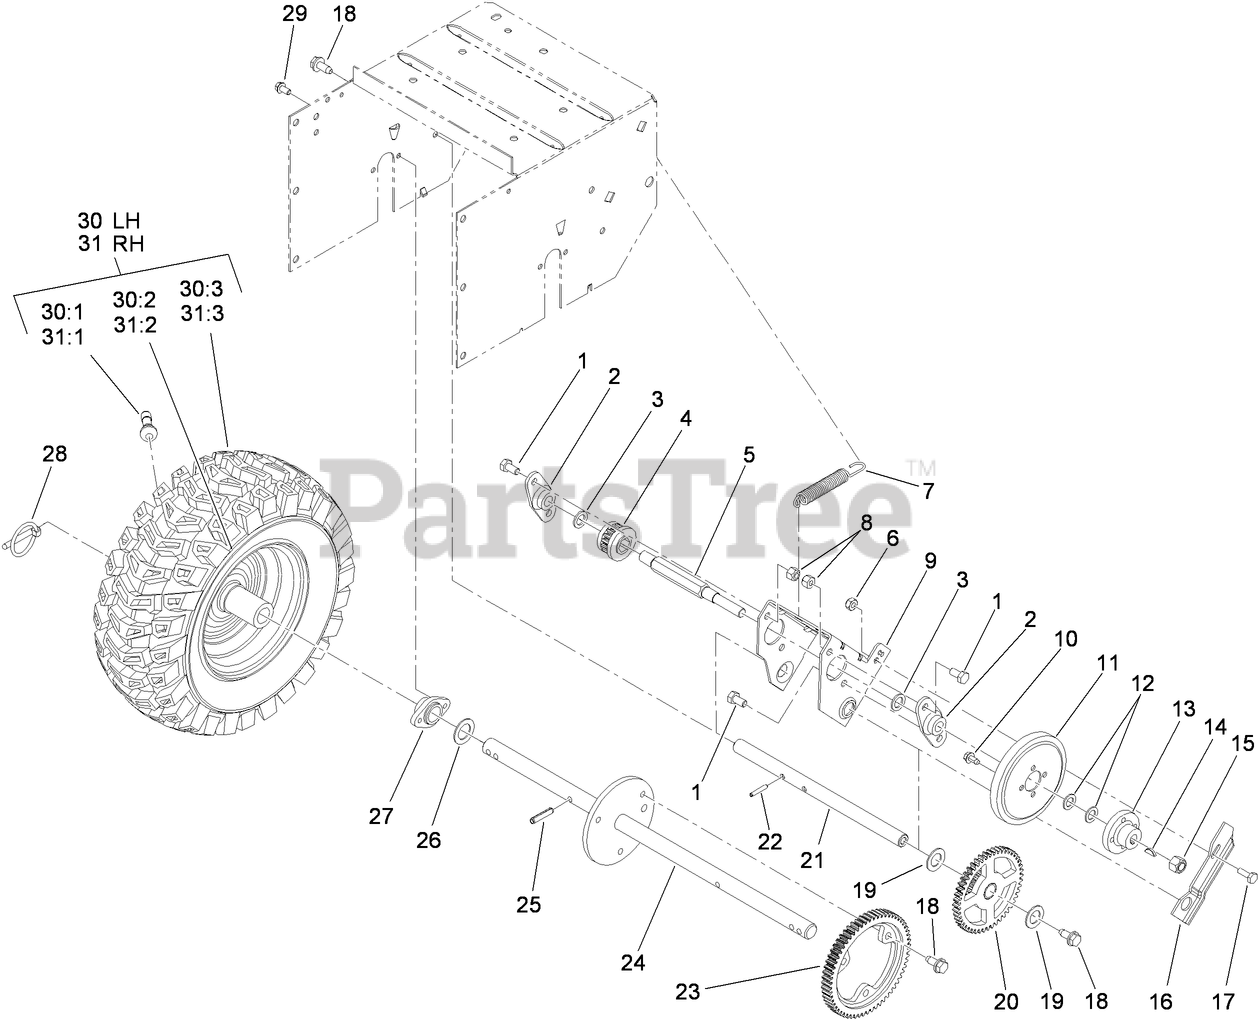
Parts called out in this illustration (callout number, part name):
1	SCREW-HH
2	BEARING-WHEEL, FRICTION
3	WASHER-FLAT
4	PINION
5	SHAFT-WHEEL, FRICTION
6	NUT-LOCK, NI
7	SPRING-TRACTION
8	NUT-LOCK, NI
9	BRACKET-SLIDING
10	SCREW-HWH
11	WHEEL-FRICTION
12	WASHER-THRUST
13	HUB-WHEEL, FRICTION
14	KEY-WOODRUFF
15	NUT-LOCK, NI
16	CAM-RECEIVER
17	SCREW-HH
18	SCREW-HWHTF
19	WASHER-SPECIAL
20	INTERNAL GEAR AND BUSHING ASM
21	SHAFT-PIVOT
22	PIN-SPRING
23	GEAR-AXLE
24	SHAFT-AXLE
25	PIN-ROLL, SLOTTED
26	WASHER-THRUST
27	BEARING-AXLE
28	PIN-LYNCH
29	SCREW-HWH
30	Loose Parts Package
30:2	RIM-WHEEL
31	Loose Parts Package
31:2	RIM-WHEEL
